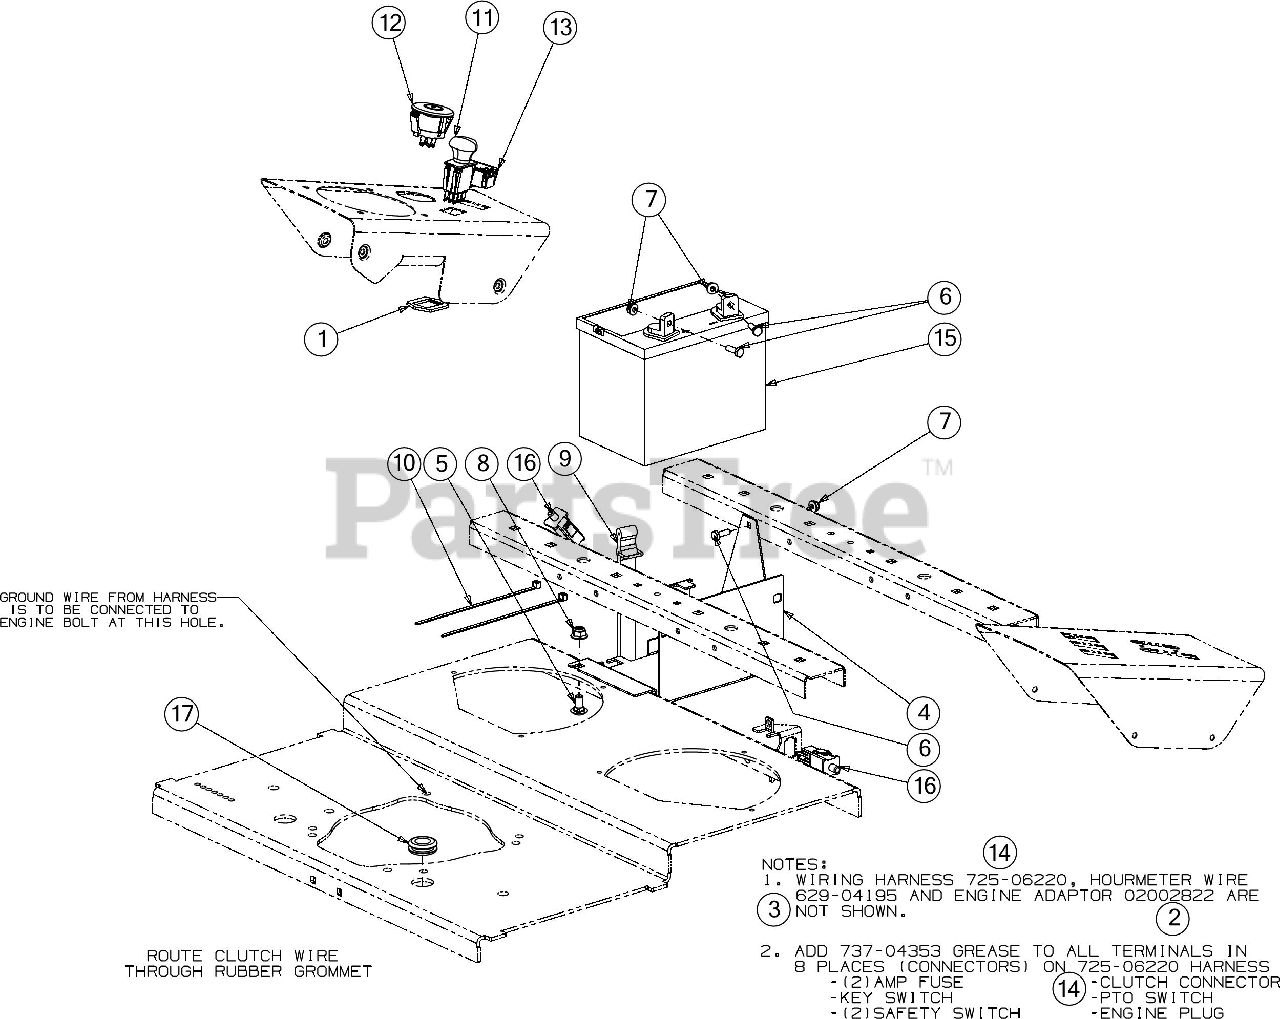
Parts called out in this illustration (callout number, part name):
1	PTO SWITCH BRACKET
2	HARNESS ADAPTER
3	HOURMETER HARNESS
4	BATTERY BRACKET
5	CARRIAGE BOLT 3/8-16 x .750 GR5
6	SCREW 1/4-20X.75 GR5
7	FLANGE LOCK NUT
9	BATTERY RETAINER STRAP
10	7" CABLE TIE
11	ELECTRIC PTO SWITCH
12	KEY SWITCH 3 POSITION
16	PLUNGER SWITCH
17	RUBBER GROMMET
